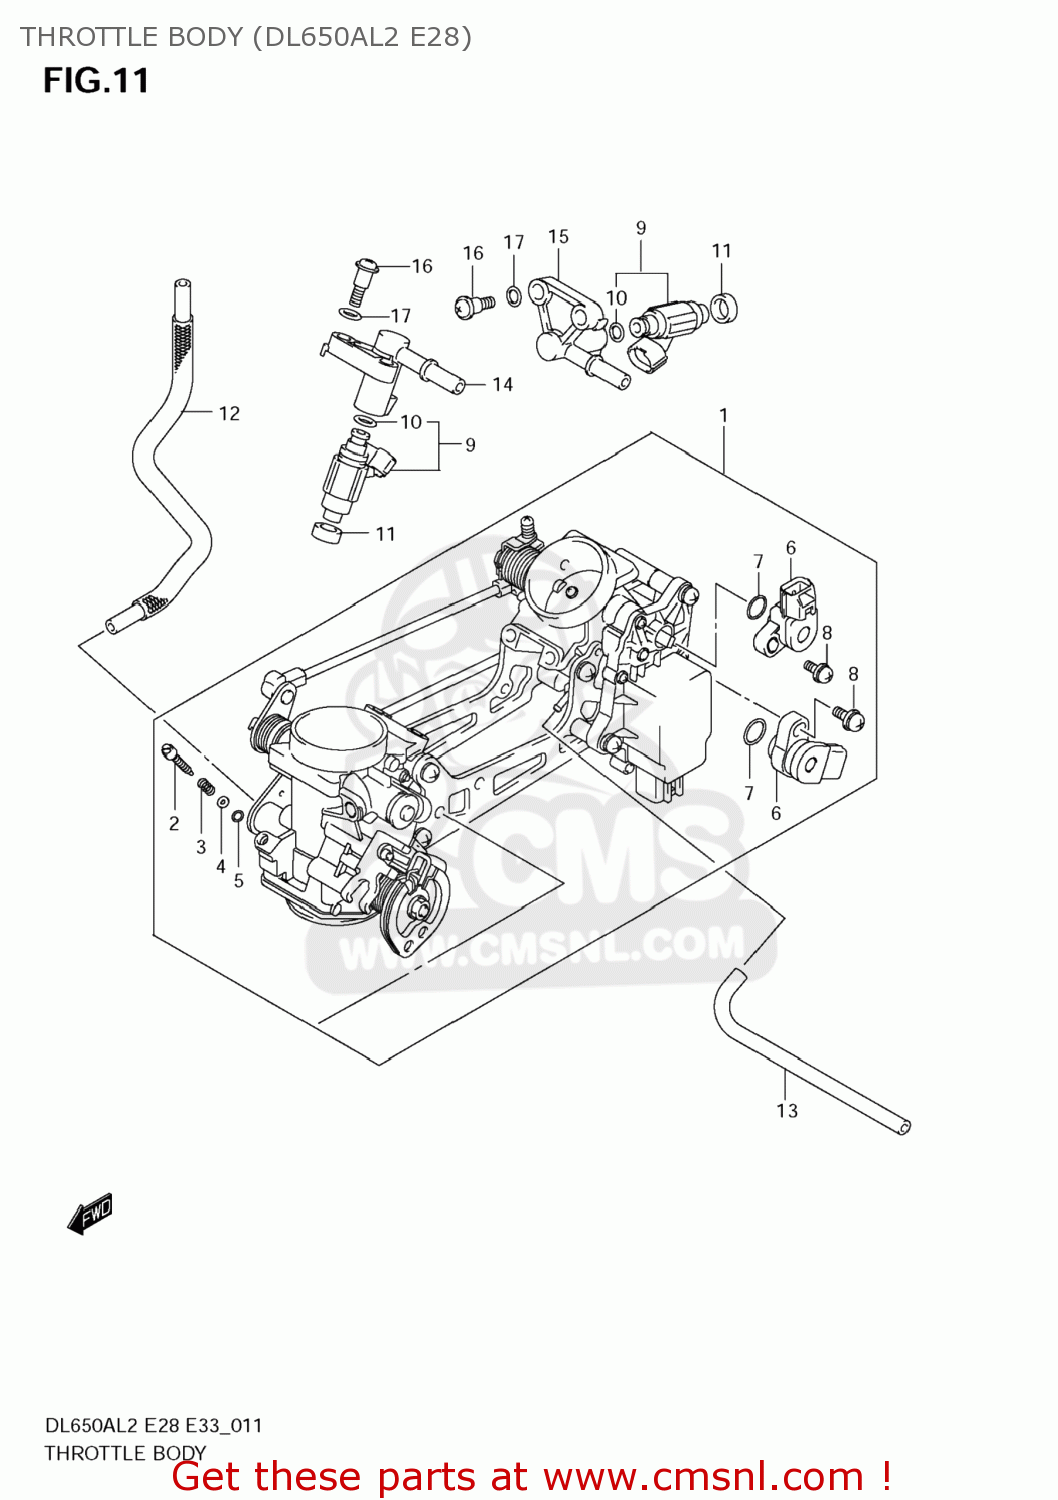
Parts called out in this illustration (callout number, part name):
1	BODY ASSY,THROTTLE
2	SCREW
3	SPRING,THROTTLE SCREW
4	WASHER
5	O RING,PILOT AIR SCREW
6	SENSOR
7	O RING
8	SCREW
9	INJECTOR ASSY
10	O-RING
11	SEAL
12	HOSE
13	HOSE
14	DELIVERY PIPE
15	DELIVERY PIPE
16	SCREW
17	PACKING (NAS)
